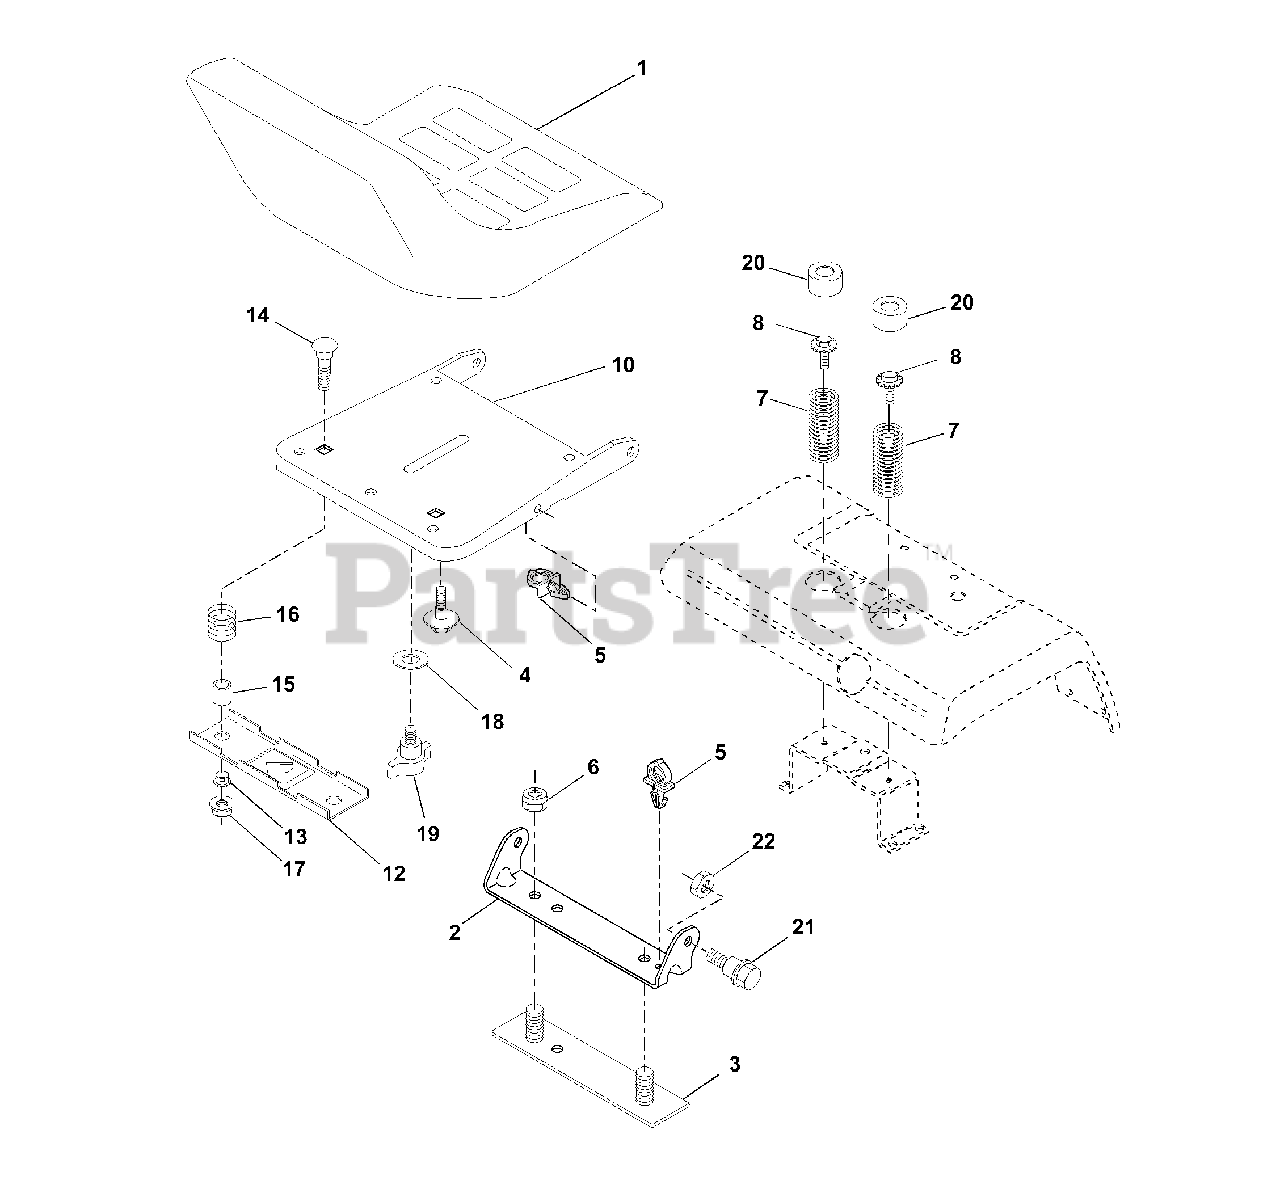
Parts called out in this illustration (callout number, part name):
1	Seat
2	Bracket, Pivot Seat
3	Strap, Fender
4	Bolt, Shoulder 5/16-18 X .62
5	Clip, Push In Hinged
6	Nut, Crownlock 3/8-16
7	Spring, Seat Cprsn
8	Bolt 5/16-18 UNC X 3/4
10	Pan, Seat
12	Bracket, Mounting Switch
13	Bushing, Snap
14	Bolt, Carriage 1/4-20 X 1-1/2
15	Spacer, Split
16	Spring, Cprsn
17	Nut, Lock 1/4 Lge Flg Gr. 5
18	Washer 17/32 X 1-3/16 X 12 Ga.
19	Knob, Seat
20	Cap, Spring Seat
21	Bolt, Shoulder 5/16-18
22	Nut, Crownlock 5/16-18
